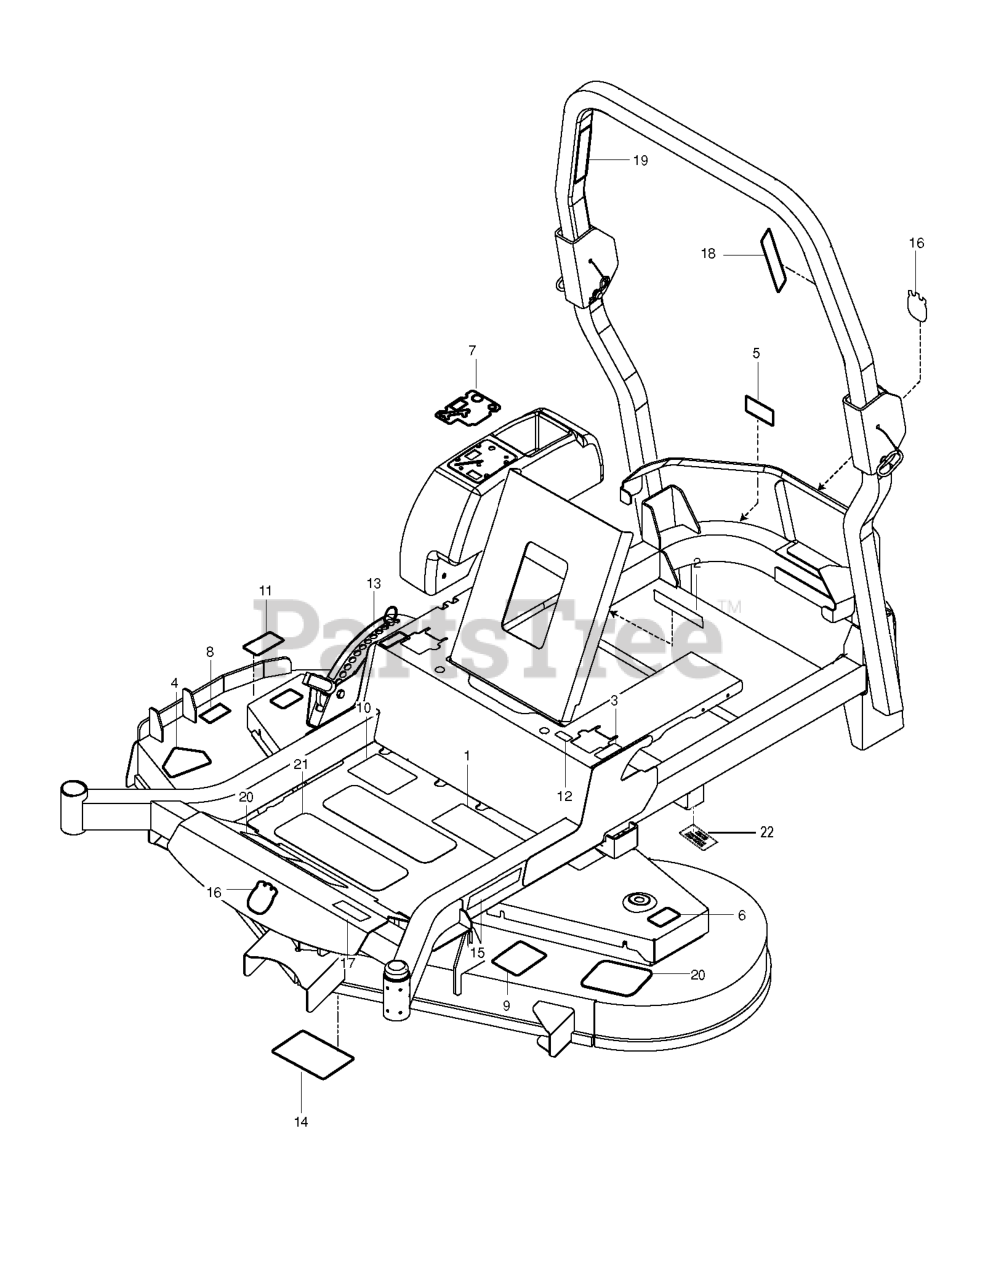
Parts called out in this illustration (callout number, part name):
1	DECAL.ZTR.WARNING.SMARTIGNITIN
1	DECAL, WARNING
2	EURO DECAL-BATTERY WARNIN6
3	DECAL.ZTR.MOTCONTRL.SYMBOL.HUS
4	DECAL, CPSC
4	DECAL, DECK DEFLECTOR, WARNING
5	DECAL, BELT DRIVE
6	DECAL, NO STEP
6	DECAL.DECK.6MIL.EURO.NOSTEP
7	DECAL, CONSOLE HUS
8	DECAL, EURO SEVERING
9	DECAL, BELT ROUTING
10	DECAL.ZTR.STRTNGINST.REMOTECHK
10	DECAL, WARNING
11	DECAL.DECK.6MIL./DEF.SHLD.WARN
11	DECAL, CAUTION
12	DECAL.STR.S.T.SYSMBOLONLY.2014
13	DECAL, HEIGHT ADJUST
14	DECAL, SERVICE
15	RP.DECAL.BADGE.170MM.TEXTLOGO
16	DECAL.AUGER.HUSQ.CROWN.SNOW
17	DECAL.ZTR.MZT52.HUSQVARNA
18	DECAL ROPS
19	DECAL, ROPS, WARNING
21	ANTI-SKID PAD
22	DECAL ZTR MZT61 HUSQVARNA
22	HG_DECAL, ZT-3400
